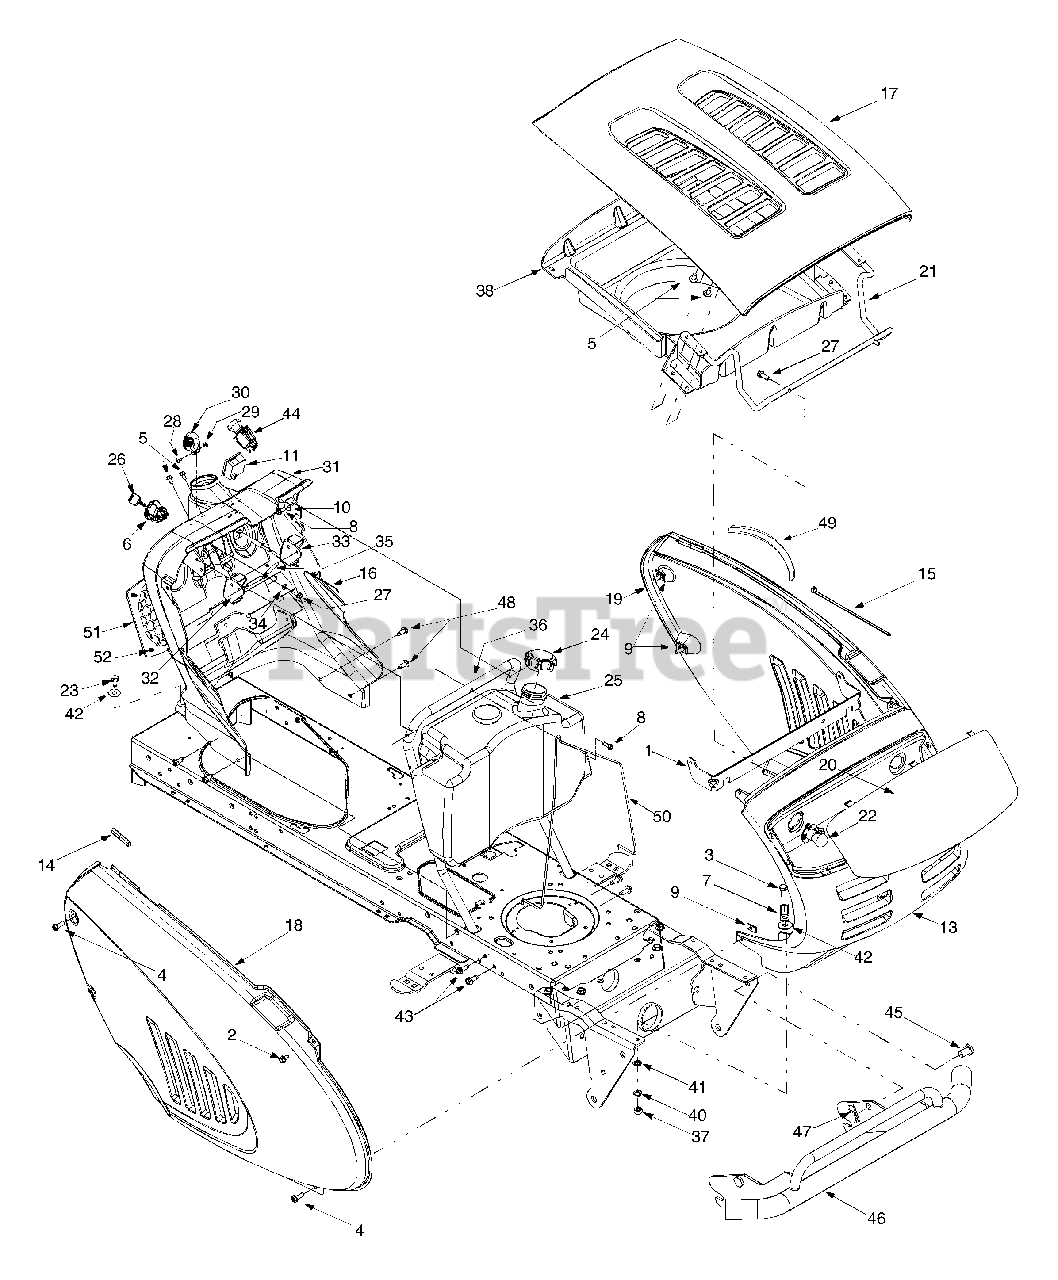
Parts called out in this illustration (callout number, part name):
2	Self-tapping Screw, 1/4-20 x .5
3	Hex Cap Screw, 5/16-18 x 1.25
4	Phillips Pan Screw, 1/4-20 x .75
5	Truss Phillips Screw, 1/4-20 x .625
6	Ignition Switch
7	Clamp, 9/16
8	Self-tapping Screw, 1/4-20 x .75
9	U-type Speed Nut, 1/4-20
10	Bell Washer, .265 x .75 x .062
11	Systems Indicator Monitor
13	Grille (9-style)
14	Trim Strip, 4
15	Cable Tie, 3/16 x .05 x 7.4
16	Choke Knob/Cable
21	Hood Hinge Rod
22	Headlight Assembly
23	AB Screw, 5/16-12 x .75
24	Fuel Cap
25	Fuel Tank, 3 gallon
26	Ignition Key w/ plastic cover
27	Self-tapping Screw, 1/4-15 x .75
28	Truss Phillips Screw, #8-32 x .375
29	Hex Nut, #8-32
30	Throttle Control Knob
31	Dash Panel, 8/9-style, Electric PTO
32	Cruise Control Button
33	Parking Brake Button
34	Flat Washer, 9/32 x 1/2 x 1/16
35	Brake/Cruise Pivot Rod
36	Dash Support Tube
37	Hex Nut, 5/16-18
38	Hood Plenum
40	Lock Washer, 5/16
41	Speed Nut, .3125
42	Flat Washer, .349 x 1.0 x .063
43	TT Screw, 5/16-18 x .875
44	Electric PTO Switch
45	Clevis Pin, .50 x .78
46	Bumper Assembly
47	Internal Cotter Pin
48	TT Screw 5/16-18 x 0.75
49	Seal: Panel
50	Tank Support Rod
52	Ratchet Clip
